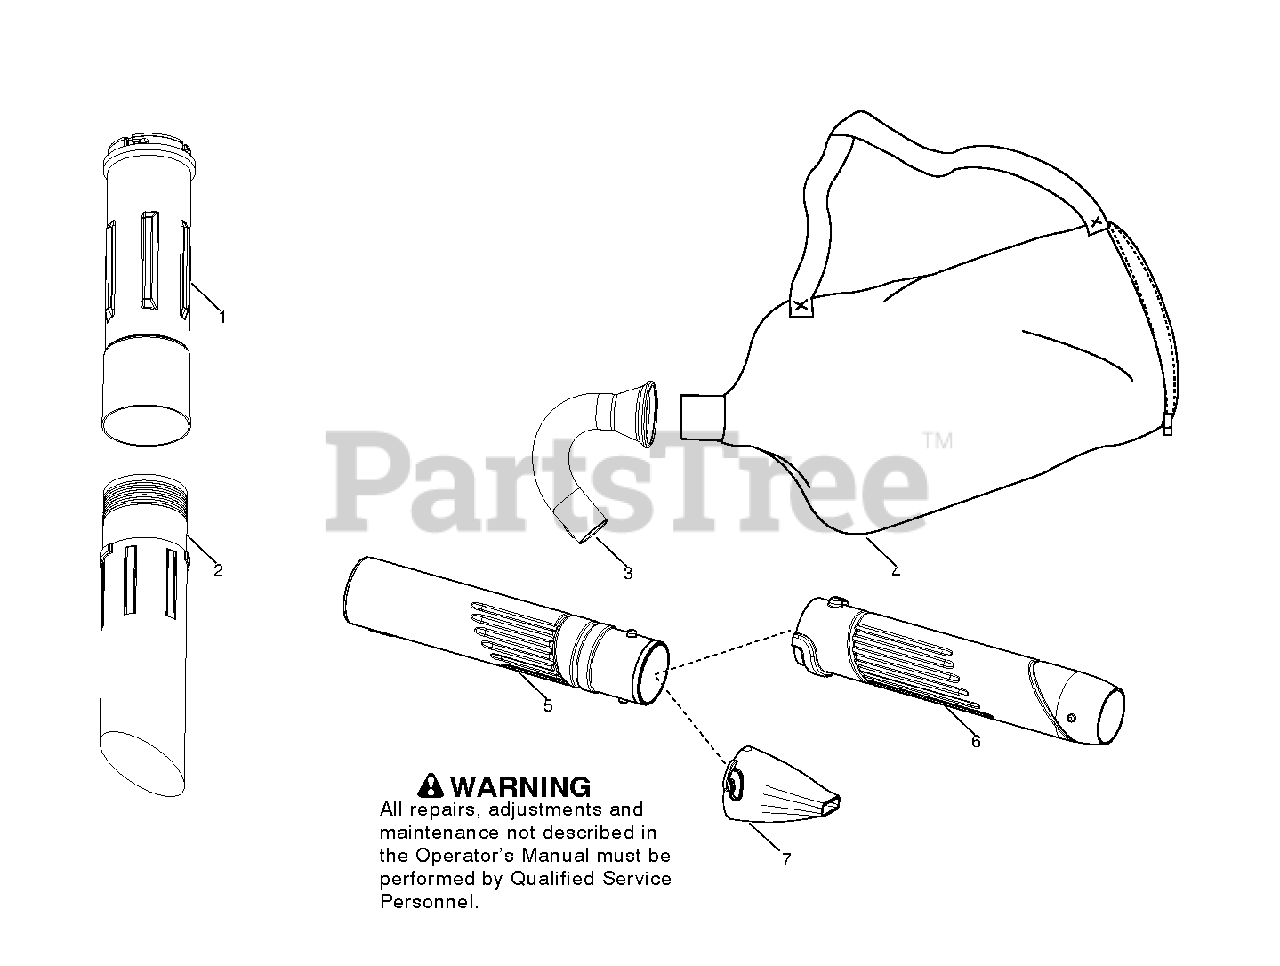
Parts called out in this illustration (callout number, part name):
1	TUBE VAC UPPER BLACK
2	TUBE LOWER VAC
3	TUBE VACUUM J BLACK
4	ASSY VAC BAG GAS W/STRAP
5	TUBE BLOWER SUPPER W BLACK
6	TUBE BLOWER LOW END BLACK
7	NOZZLE BLACK HI SPEED ADAPTOR
